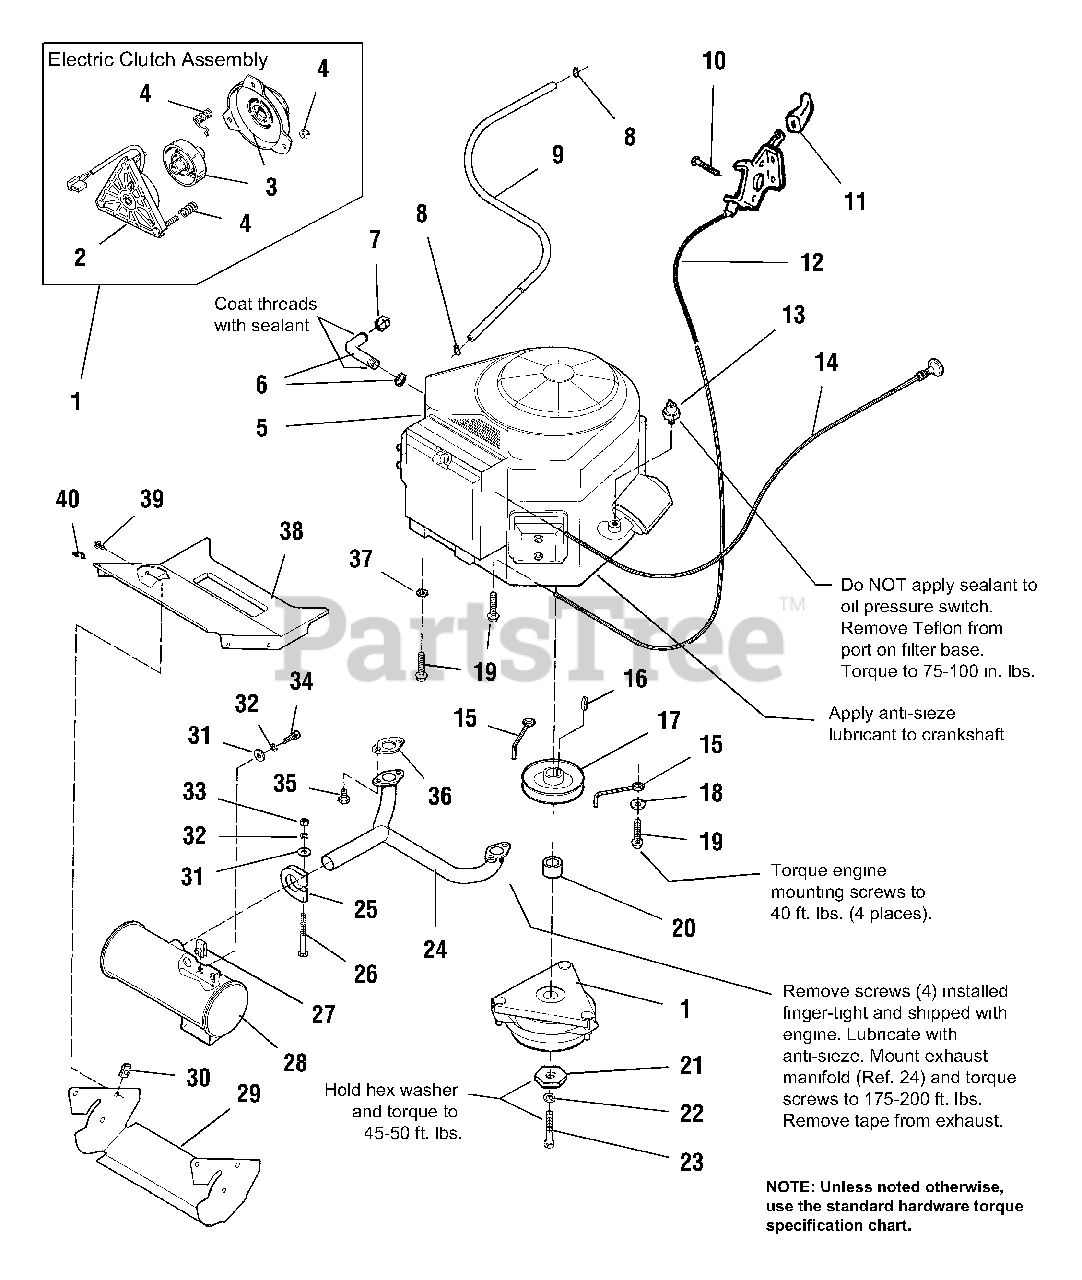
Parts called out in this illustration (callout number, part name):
1	ELECTRIC CLUTCH (Incl. Ref. Nos. 2, 3, & 4)
2	FIELD ASSY., Clutch
3	ROTOR ASSY./ARMATURE KIT
4	SPRING & NUT KIT
8	CLAMP, Hose
9	HOSE, Fuel, 45.5" Long
10	SCREW, Plastite, 1/4-10 x 1/2
11	KNOB, Throttle
12	THROTTLE & CABLE ASSY.
13	SWITCH, Oil Pressure
14	CABLE, Choke Control
16	KEY, Hi-Pro
17	PULLEY ASSY.
18	WASHER, Plain, 13/32
19	SCREW, Taptite, 3/8-16 x 1-1/2
22	LOCKWASHER, 7/16
23	CAPSCREW, 7/16-20 x 4
24	MANIFOLD, Exhaust
25	CLAMP, Muffler
26	CARRIAGE BOLT, 5/16-18 x 2-3/4
27	NUT, Pal, 5/16-18
28	MUFFLER ASSY.
29	DUCT, Lower Muffler
30	NUT, Pal, 1/4-20
31	WASHER, Plain, 11/32
32	LOCKWASHER, 5/16
33	NUT, Hex, Full, 5/16-18
34	CAPSCREW, Hex Hd., 5/16-18 x 1
35	SCREW, Metric
36	GASKET
37	LOCKWASHER, External Tooth
38	DUCT, Upper Muffler
39	SCREW, Flange Whiz, 1/4-20 x 5/8
40	CLIP
